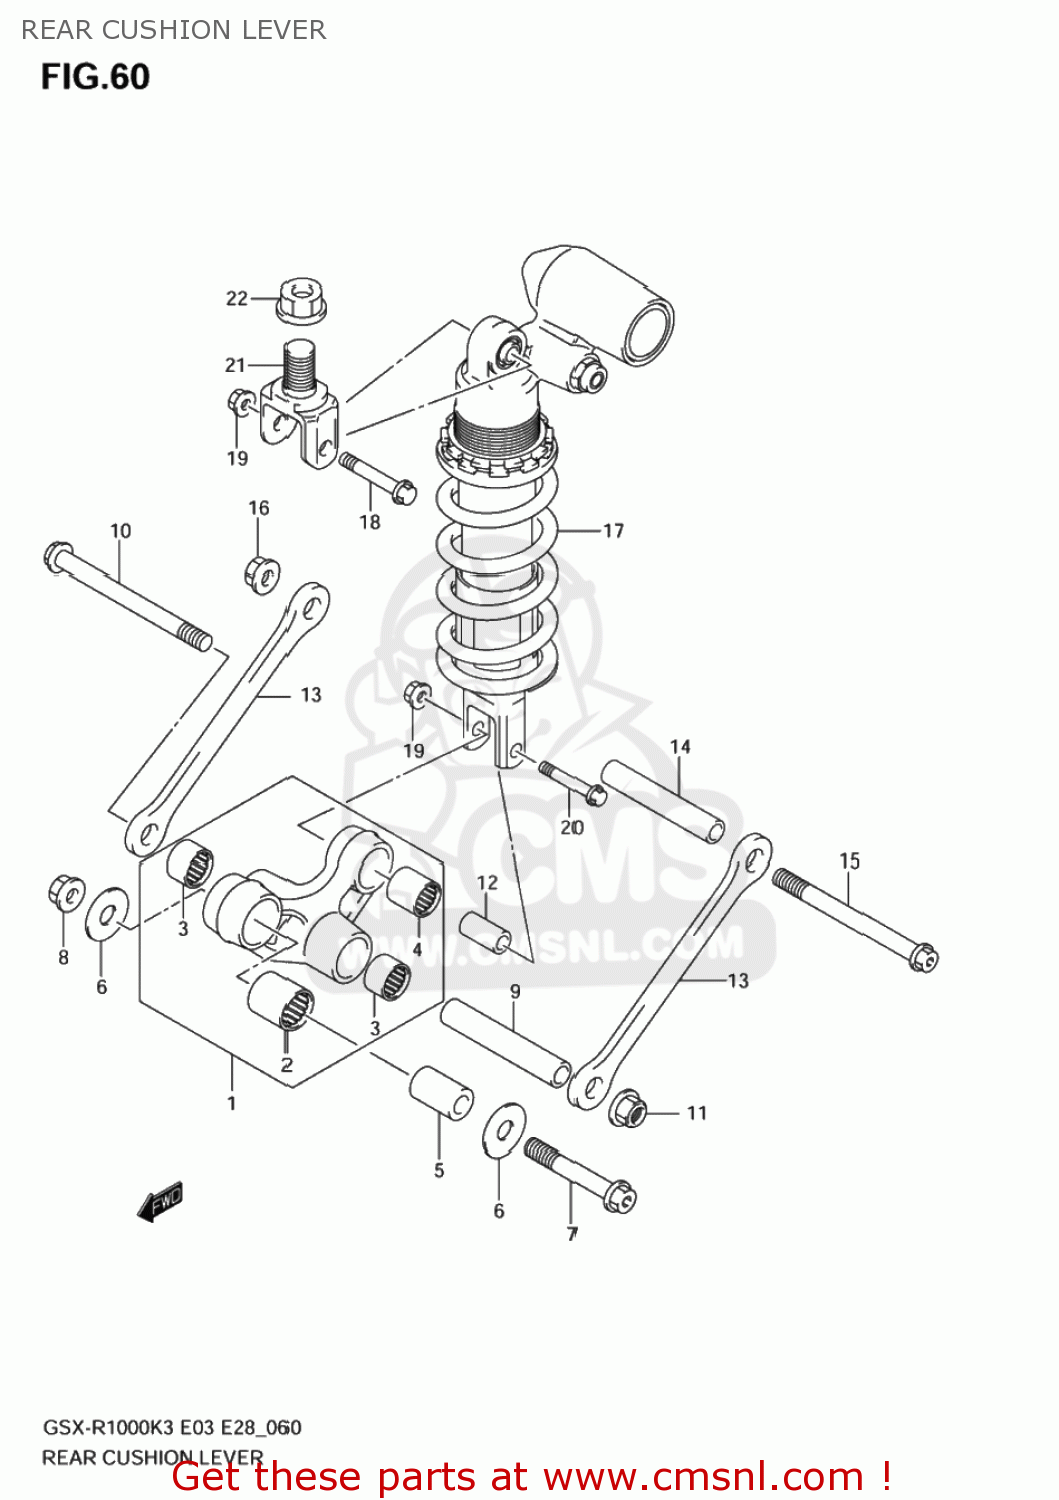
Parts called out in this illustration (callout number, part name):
1	LEVER SET,REAR CUSHION
2	BEARING(20X27X30)
3	BEARING(17X24X20)
4	BEARING(17X24X26)
5	SPACER,RR CUSHION LEVER FR
6	WASHER(12X34X1)
7	BOLT,RR CUSHION LEVER FR
8	NUT 12MM
9	SPACER,RR CUSHION LEVER CTR
10	BOLT,RR CUSHION LEVER CTR
11	NUT 12MM
12	SPACER,RR CUSHION LEVER
13	ROD,RR CUSHION
14	SPACER,RR CUSHION LEVER CTR
15	BOLT,RR CUSHION LEVER CTR
16	NUT 12MM
17	ABSORBER ASSY,RR SHOCK(YELLOW)
18	BOLT(10X55)
19	NUT
20	BOLT(10X55)
21	BRACKET,RR SHOCK ABSORBER UPR
22	NUT
